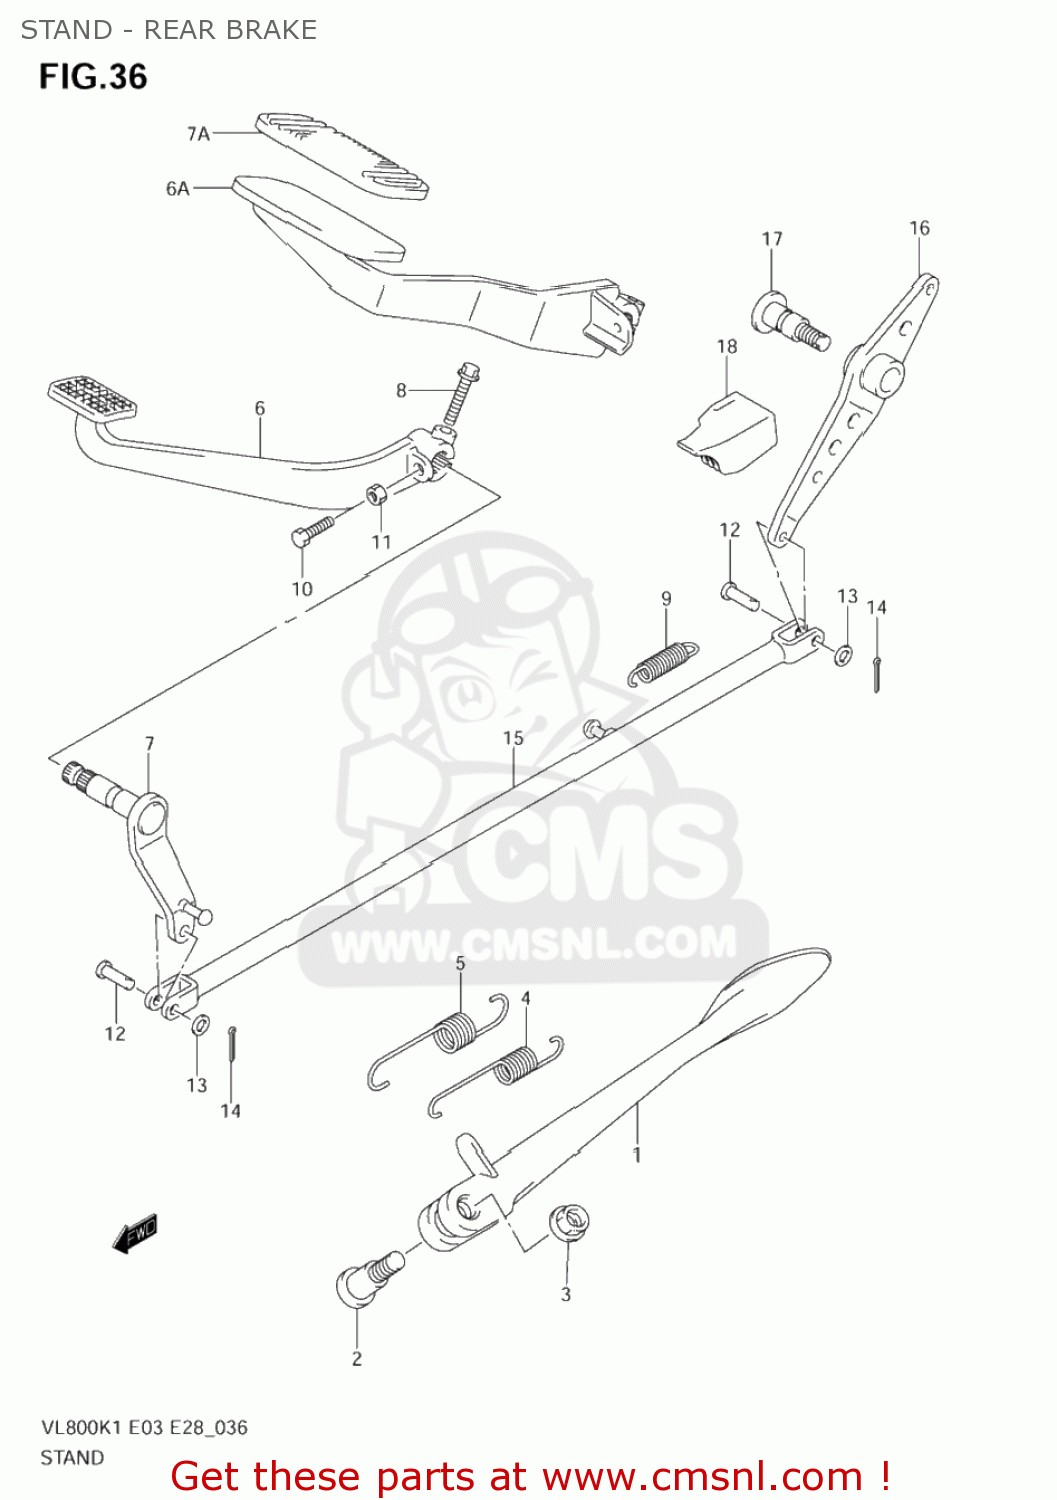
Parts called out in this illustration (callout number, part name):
1	STAND,PROP
2	BOLT(10X37.5)
3	NUT,PROP STAND
4	SPRING
5	SPRING
6	PEDAL,BRAKE
6A	PEDAL COMP,BRA
7	ARM,BRAKE ROD
7A	RUBBER,BRAKE PEDAL
8	BOLT
9	SPRING
10	BOLT
11	NUT
12	PIN
13	WASHER
14	PIN
15	ROD,RR BRAKE FR
16	LINK,RR BRAKE
17	SHAFT,BRAKE PEDAL
18	RUBBER,BRAKE LINK
